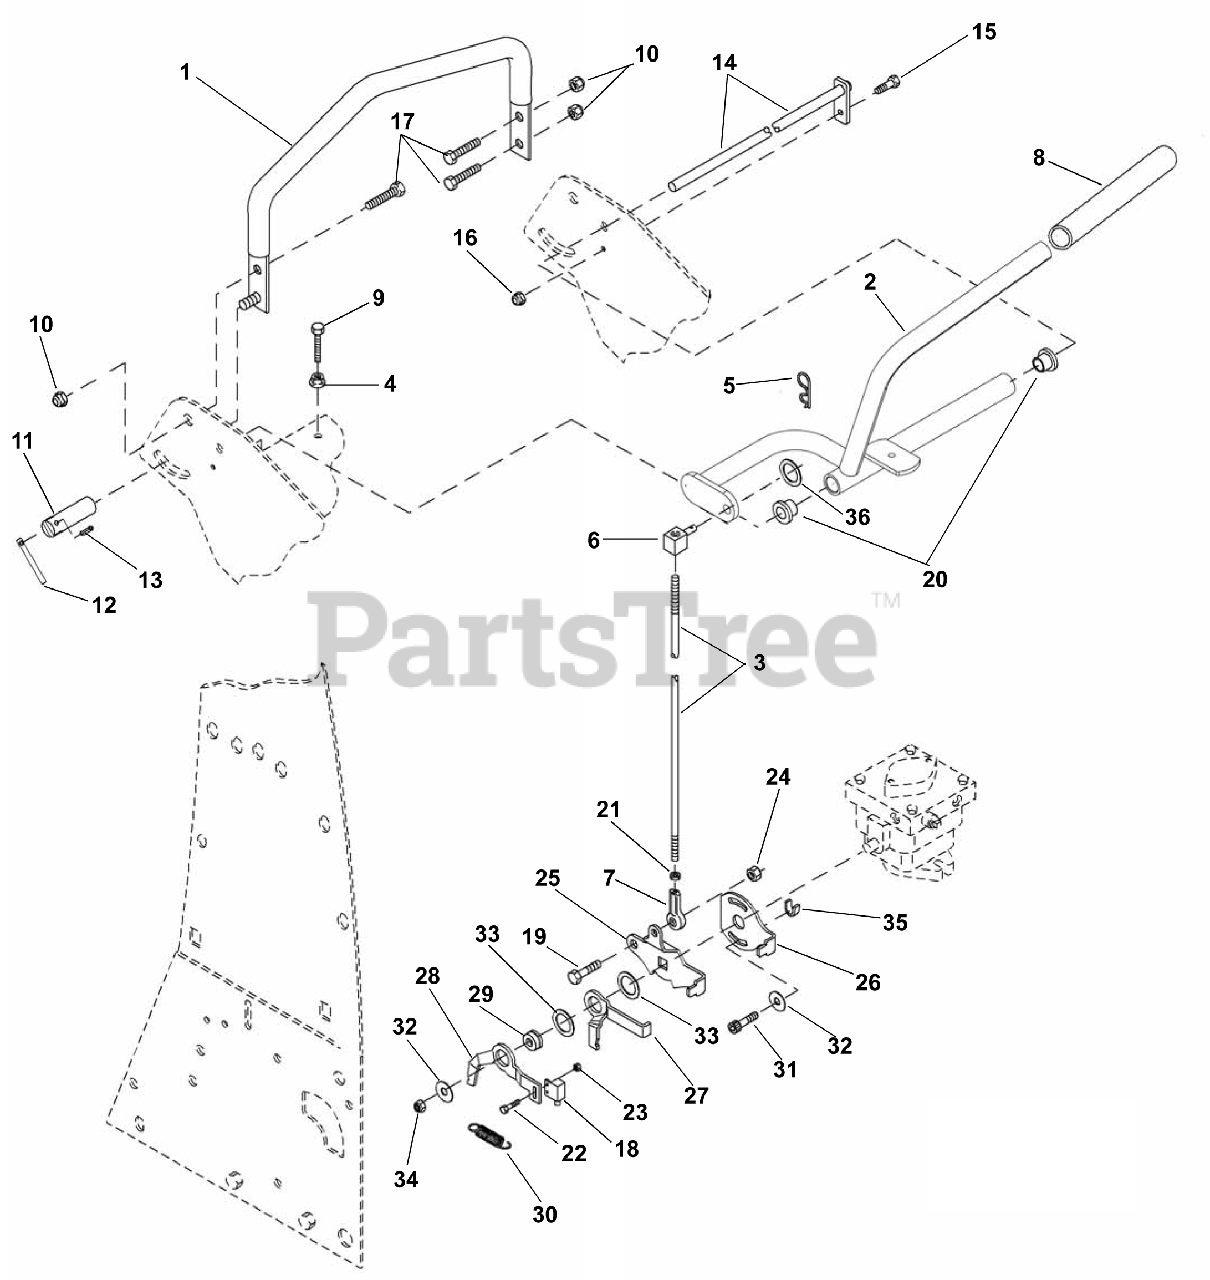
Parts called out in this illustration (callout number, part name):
1	SPEED LIMITER
2	WLDT, LH SS CONTROL LEVER
2	WLDT, RH SS CONTROL LEVER
3	CONTROL ROD
4	FLANGE NUT, M6 X 1.0
5	SPRING PIN
6	SWIVEL
7	ROD END, 5/16 RH - FEMALE
8	GRIP, CONTROL
9	CAP SCREW, REVERSE STOP M6 X 1
10	NUT-LK-NYL M10-1.5 YWZC
11	BASE, SPEED CONTROL LOCK
13	PIN, SPRING 5/32 X 1
14	SHAFT, PIVOT
15	CAP SCREW, M6 X 1.0 X 20
16	LOCKNUT,FL,ISO7043,M6X1.00-10-
17	BLT-HEX M10 X 1.5X25 YWZC
18	SWITCH, STOP (DOUBLE POLE)(N.O
19	@BLT-HEX .31-18X1.00 GR5 YWZC
20	BUSHING
21	NUT-JAM .31-24 YWZC
22	BLT-HEX M5-.8X16 YWZC
23	NUT-HEX M5X.8 PL
24	@NUT-LK-CTR .31-18 YWZC
25	ARM, CONTROL RTN
26	ARM, RETURN
27	ARM, RH INNER RTN
27	ARM, LH INNER RTN
28	ARM, LH OUTER RTN
28	ARM, RH OUTER RTN
29	SPACER
30	SPRING
31	SCREW, 5/16 X 1 PATCH LOCK
32	WASHER
33	WASHER, NYLON
34	NUT-CTRLK .31-24 YWZC
36	@WSHR-FL-STL.406X.812X.065 YWZ
